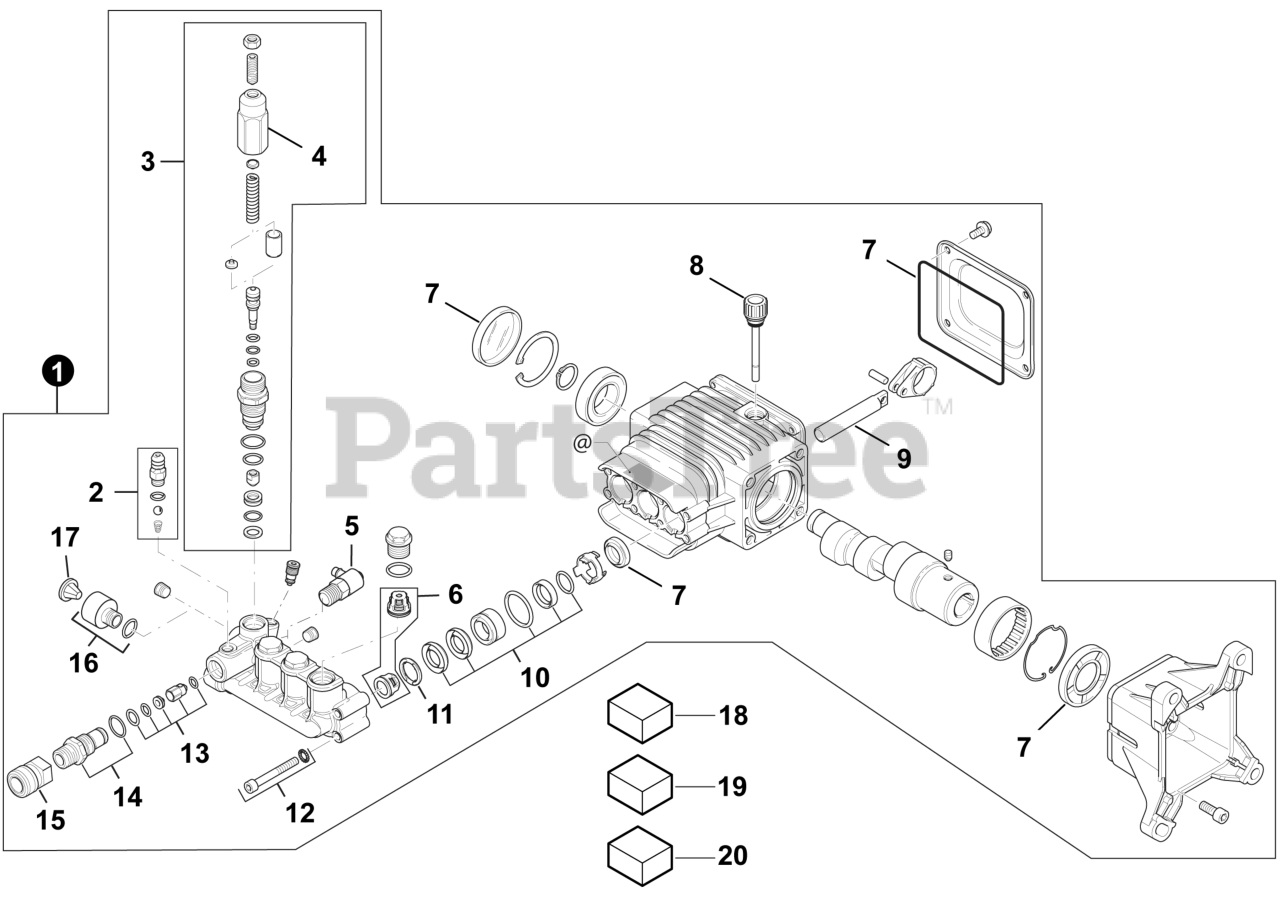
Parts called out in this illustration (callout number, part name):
1	PUMP ASSY.(AR RSV4G40HDF40EZ)
2	KIT, INJECTOR
3	KIT, UNLOADER
4	KNOB, UNLOADER
5	VALVE, THERMAL RELIEF
6	KIT, VALVE
7	KIT, OIL SEAL
8	CAP, OIL
9	KIT, PISTON
10	KIT, WATER SEAL
11	RING, SUPPORT
12	BOLT, PUMP MOUNTING W/WASHER
13	ASSY., CHECK VALVE
14	FITTING, OUTLET W/ O-RING
15	FITTING, Q/C 3/8"" FNPT
16	ADAPTOR, GARDEN HOSE INLET
17	FILTER, INLET SCREEN
18	O-RING, 1/4" - 100 Pack
19	O-RING, 3/8" - 100 Pack
20	KIT, O-RING
